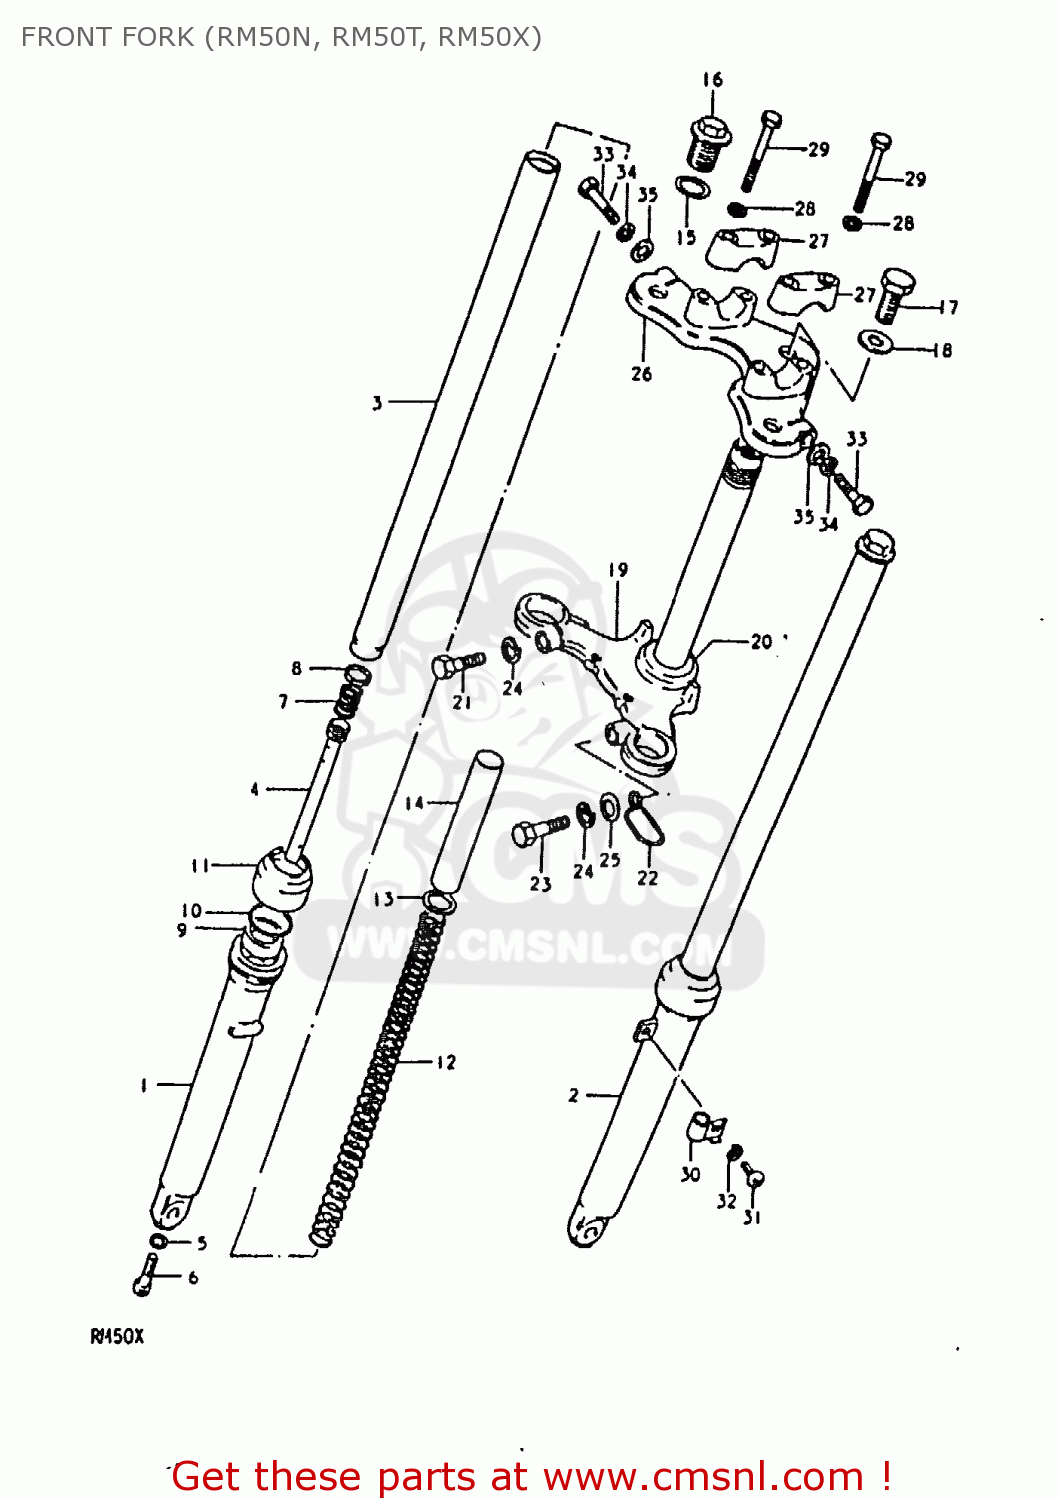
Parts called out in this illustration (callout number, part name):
1	TUBE,OUTER,RIGHT
2	TUBE,OUTER,LEFT
3	TUBE,FORK,INNER
4	CYLINDER,FRONT FORK
5	GASKET (NAS)
6	BOLT(8X27)
7	SPRING,REBOUND
8	RING,PISTON
9	OIL SEAL,FRONT FORK
10	CIRCLIP,FORK OIL SEAL
11	DUST SEAL
12	SPRING
13	JOINT,SPRING
14	SPACER,SPRING
15	O-RING,FORK INNER TUBE
16	CAP,FORK
17	BOLT
18	WASHER(10.5X30X2.3)
19	STEM,STEERING
20	RACE,STEERING OUTER LWR
21	BOLT 10X30
22	CLAMP,METER CABLE
23	BOLT,M10X1.25X
24	LOCK WASHER
25	WASHER
26	HEAD,STEERING STEM
27	HOLDER,HANDLEBAR
28	LOCK WASHER
29	BOLT
30	CLIP,CABLE
31	SCREW
32	LOCK WASHER
33	BOLT 8X40
34	LOCK WASHER
35	WASHER
